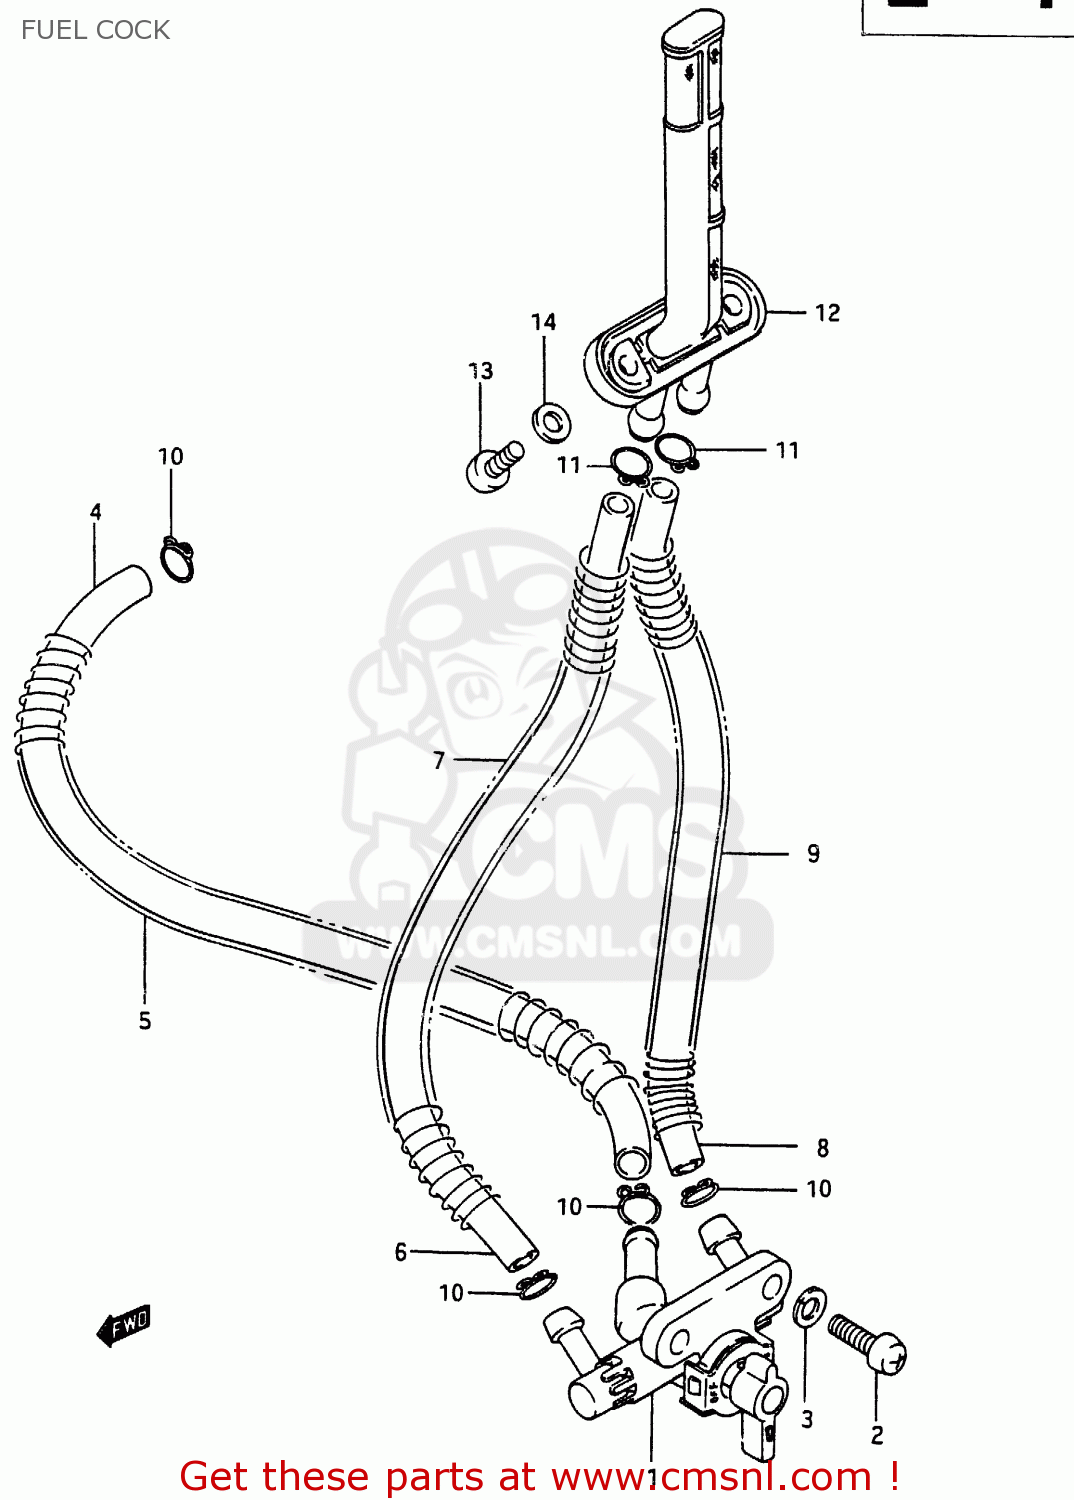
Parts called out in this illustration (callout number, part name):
1	COCK ASSY, FUEL
2	SCREW
3	WASHER,LOCK
4	HOSE
5	SPRING
6	HOSE
7	SPRING
8	HOSE
9	SPRING
10	CLIP
11	CLIP
12	UNIT, FUEL FILTER
13	BOLT(6X20)
14	GASKET
